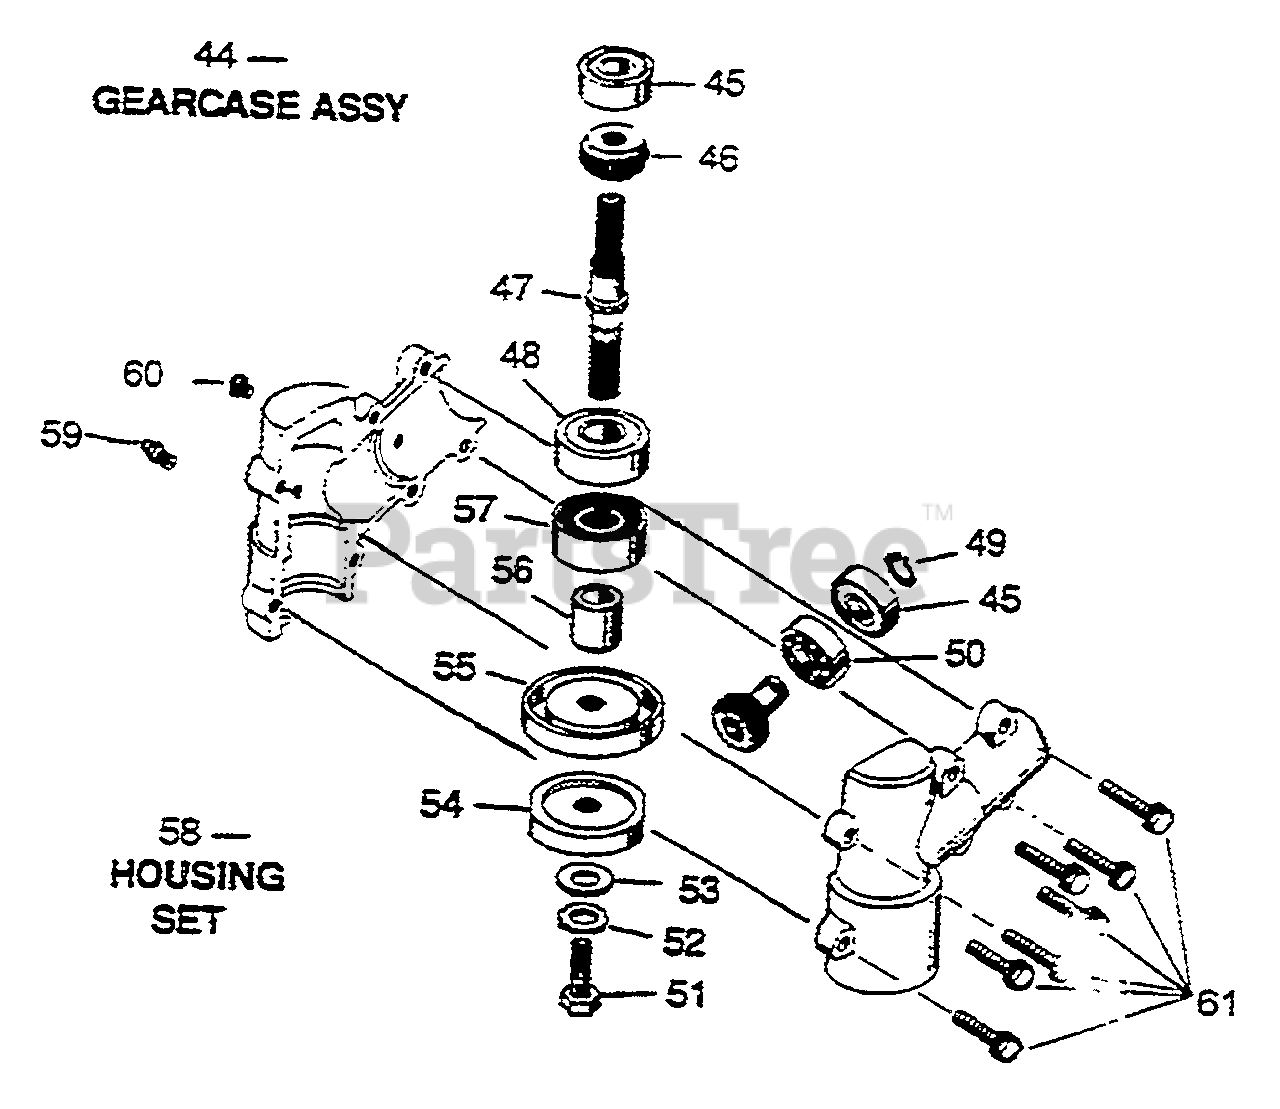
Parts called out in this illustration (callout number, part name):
44	GEARCASE ASSY
45	BEARING
46	GEAR SET KIT
47	SHAFT, GEAR
48	BEARING
49	SNAP RING
50	BEARING
51	BOLT
52	WASHER
54	HOLDER B
58	HOUSING SET
59	ZERK FITTING
60	SCREW, SELF TAPPING
61	SCREW, SELF TAPPING
